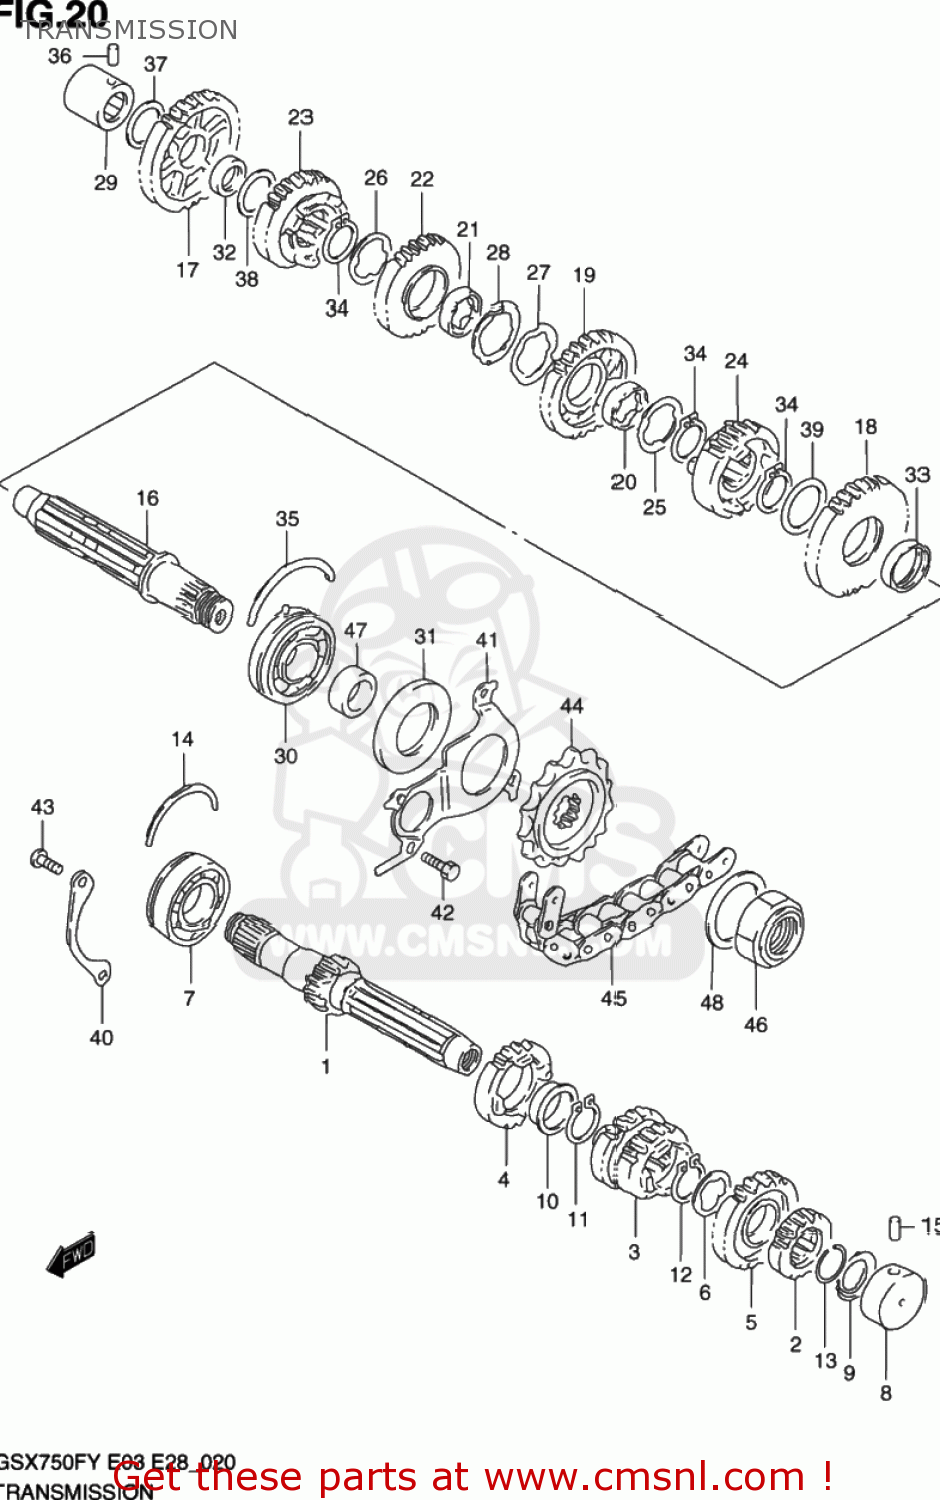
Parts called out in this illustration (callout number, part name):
1	SHAFT,COUNTER(NT:12)
2	GEAR,2ND DRIVE(NT:16)
3	GEAR,3RD & 4TH DRIVE(NT:17/20)
4	GEAR,5TH DRIVE(NT:22)
5	GEAR,6TH DRIVE(NT:21)
6	WASHER,LOCK
7	BEARING(25X62X17)
8	BEARING(20X34X17.5)
9	SEAL,OIL(20X31.2X2.7)
10	BUSHING
11	RING,SNAP
12	RING,SNAP
13	CIRCLIP
14	C RING
15	PIN
16	SHAFT,DRIVE
17	GEAR,1ST DRIVEN(NT:37)
18	GEAR,2ND DRIVEN(NT:33)
19	GEAR,3RD DRIVEN(NT:28)
20	BUSH
21	BUSH
22	GEAR,4TH DRIVEN(NT:28)
23	GEAR,5TH DRIVEN(NT:27)
24	GEAR,6TH DRIVEN(NT:23)
25	WASHER,LOCK
26	WASHER,LOCK
27	WASHER,LOCK
28	WASHER
29	BEARING(20X34X20)
30	BEARING(25X62X21.6)
31	SEAL,OIL(34X62X6)
32	BUSH(22X26X9)
33	BUSH(28X32X9.5)
34	CIRCLIP
35	C RING
36	PIN
37	SHIM(20X34X1)
38	SHIM(22X34X1)
39	SHIM(28X38X1)
40	RETAINER,CNTR SHAFT BEARING
41	RETAINER,DRIVE SHAFT OIL SEAL
42	BOLT
43	SCREW ,6X16
44	SPROCKET,ENGINE(NT:15)
45	CHAIN ASSEMBLY RK50MF0Z1.1
46	NUT
47	SPACER(25X34X17.5)
48	SHIM(25X40X1.5)
